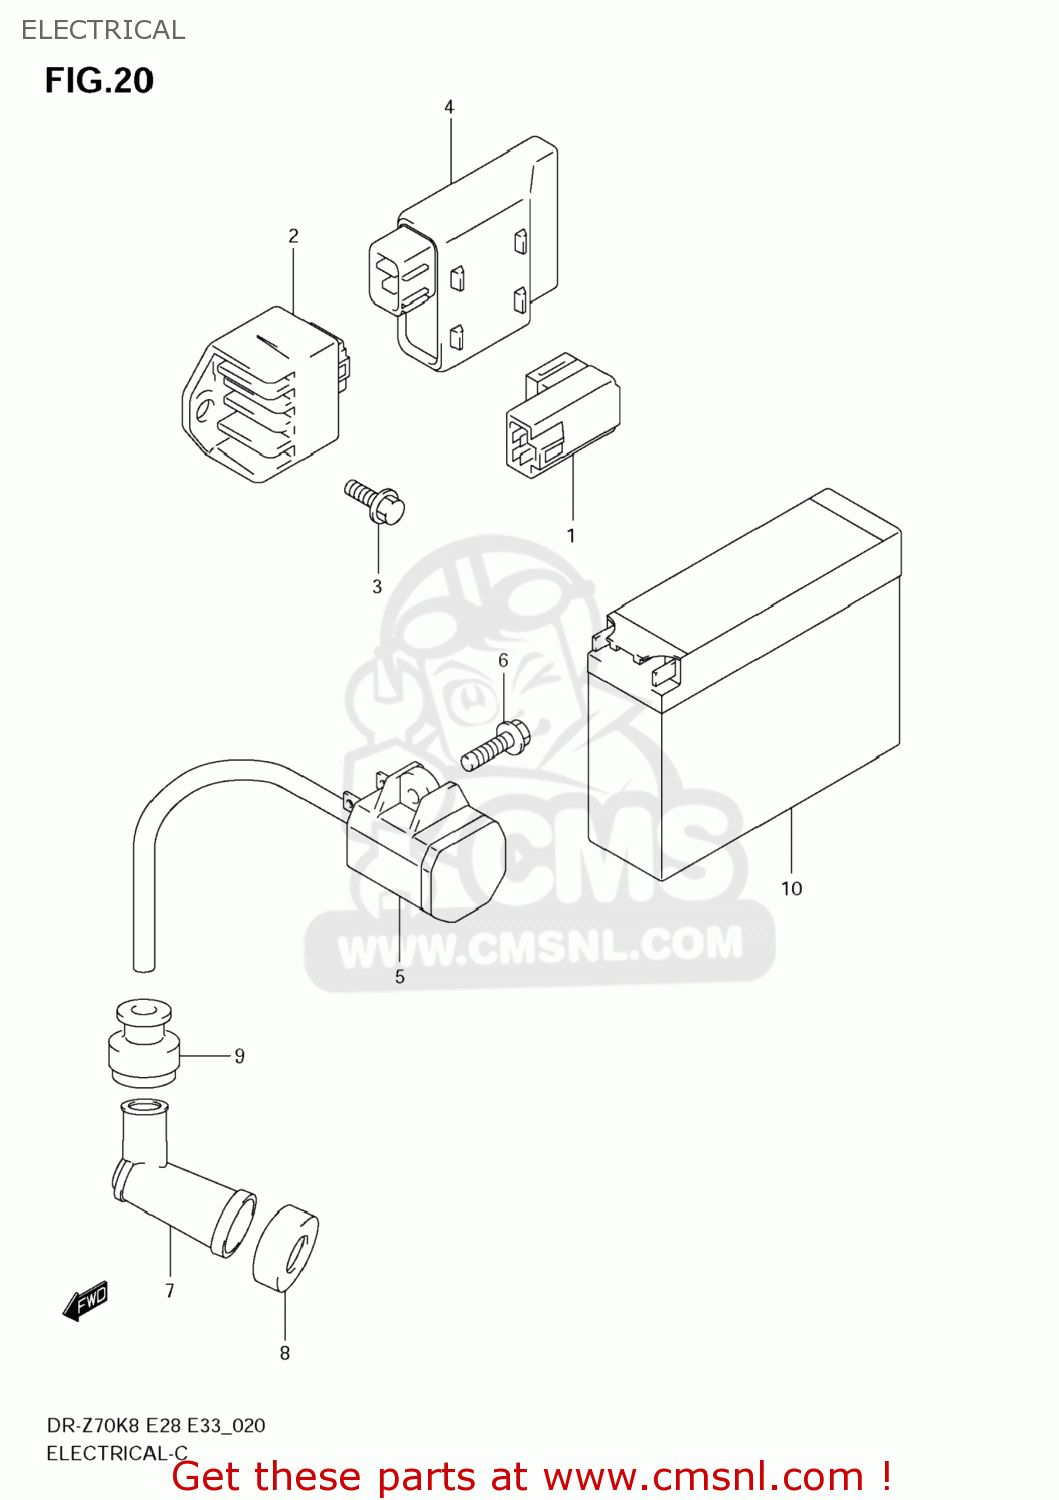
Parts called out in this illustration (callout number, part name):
1	RELAY ASSY,STARTING MOTOR
2	RECTIFIER ASSY
3	SCREW
4	CDI UNIT
5	COIL ASSY,IGNITION
6	SCREW
7	CAP ASSY,SPARK PLUG
8	SEAL,SPARK PLUG
9	SEAL,HIGH TENSION CORD
10	BATTERY ASSY(YT4B-BS,12V2.4AH)
